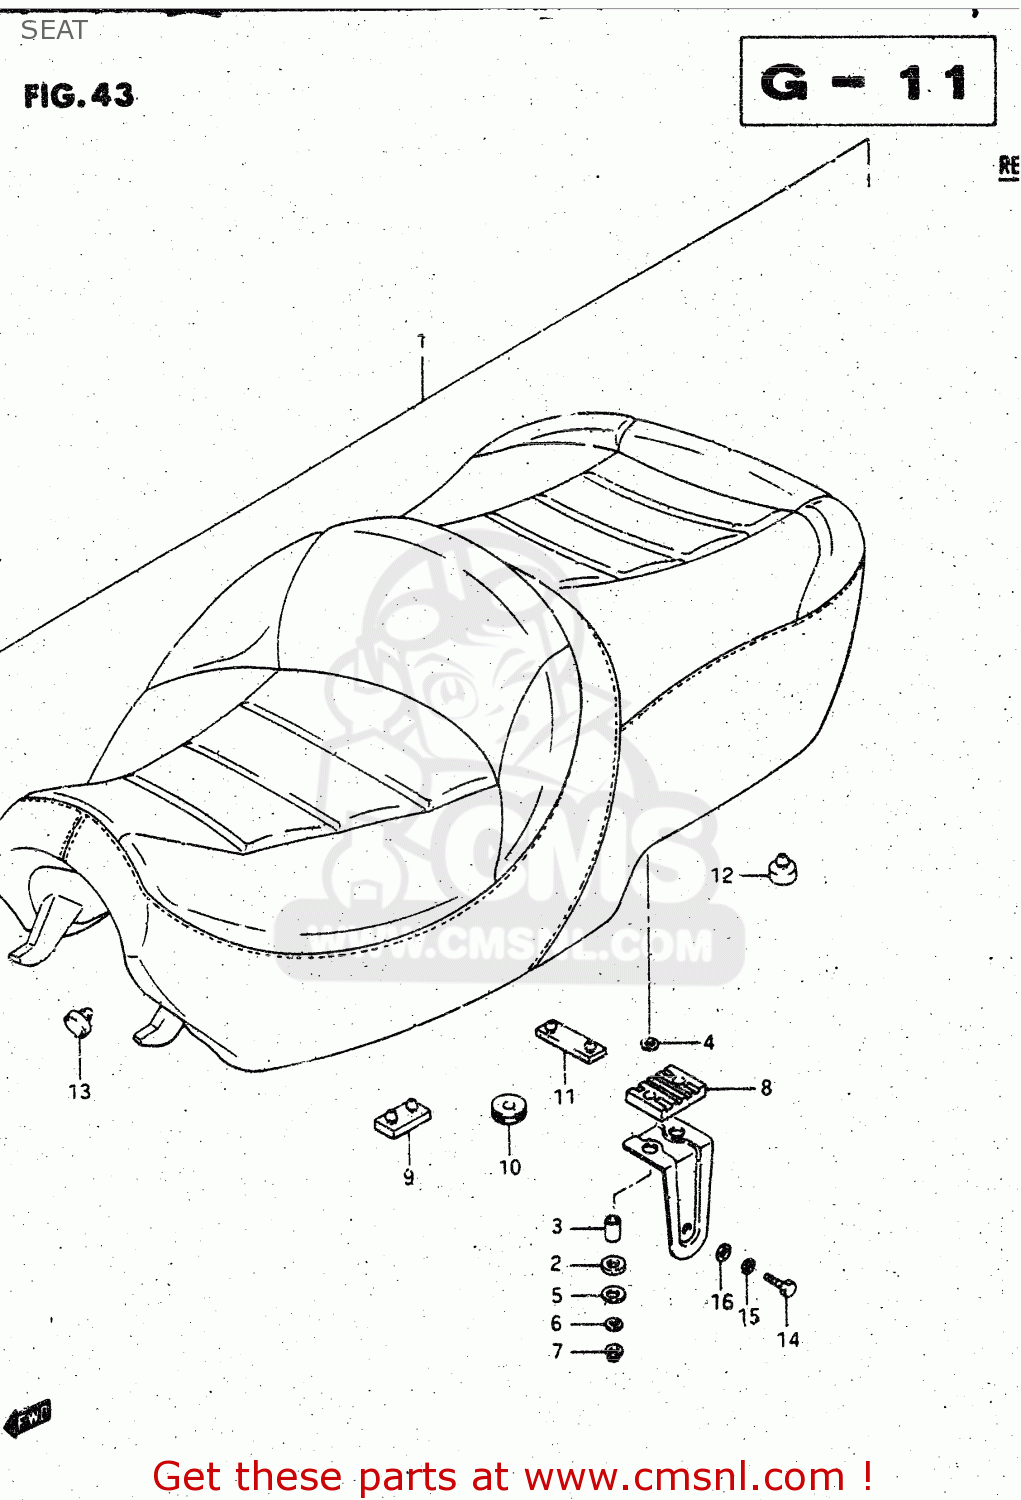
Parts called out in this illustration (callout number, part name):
1	SEAT ASSEMBLY
2	CUSHION,SEAT FR
3	SPACER,SEAT SUPPORT
4	WASHER
5	WASHER, LOWER
6	WASHER,LOCK
7	NUT
8	CUSHION,FR PLATE
9	CUSHION,SEAT(40X20X15)
10	CUSHION
11	CUSHION
12	CUSHION
13	CUSHION
14	BOLT
15	WASHER,LOCK,8.
16	WASHER
